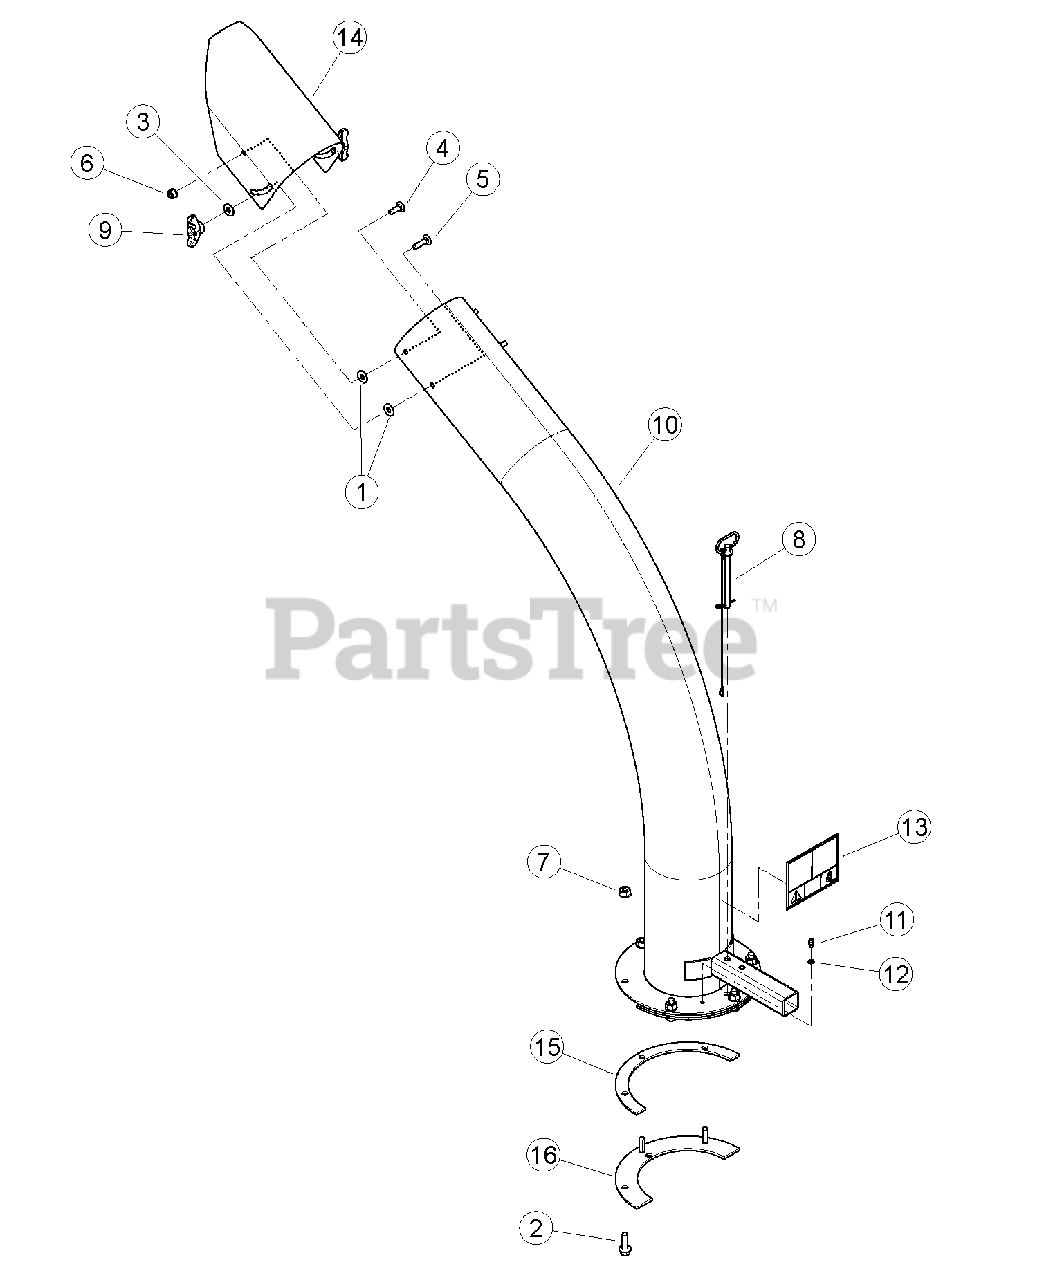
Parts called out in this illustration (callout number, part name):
1	WASHER, 3/8 FLAT
2	BOLT, 3/8 X 1-1/4 FLANGE NC
3	WASHER, 5/16" FLAT ZP
4	BOLT, 5/16" X 1" GR5 CRG ZP
5	BOLT, 5/16 X 1-1/4" GR5 CRG ZP
6	NUT, 5/16-18 NYLOCK FLANGE
7	NUT, 3/8-16 NYLOCK FLANGE
8	PIN, 3/8 X 4.25" DISCHARGE
9	KNOB, 5/16-18 UNC TEE W/ LOCKING INSERT
10	ASSEMBLY, 6 INCH DISCHARGE CHUTE
11	FITTING, 1/4 SELF-TAP GREASE
12	WASHER, FLAT .254 X .400 X .048
13	DECAL, DISCHARGE DEBRIS & LOCK
14	DEFLECTOR, BLOWER VAC DISCHARGE
15	SPACER, DISCHARGE PIVOT
16	RING, DISCHARGE CLAMP
